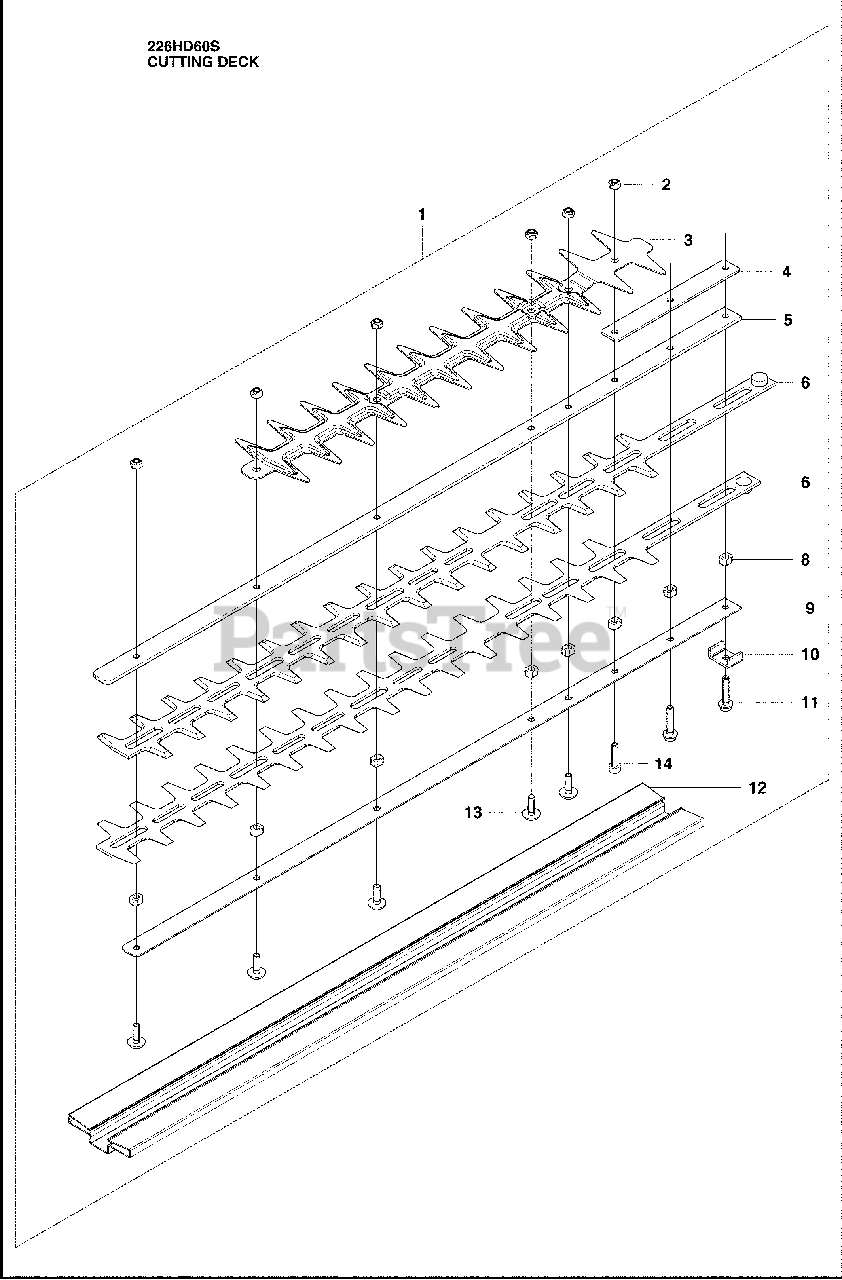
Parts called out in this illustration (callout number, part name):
1	Blade Assembly
3	Blade Guard
5	Plate
6	Blade
9	Lower Plate
12	Blade Cover
14	Bolt
